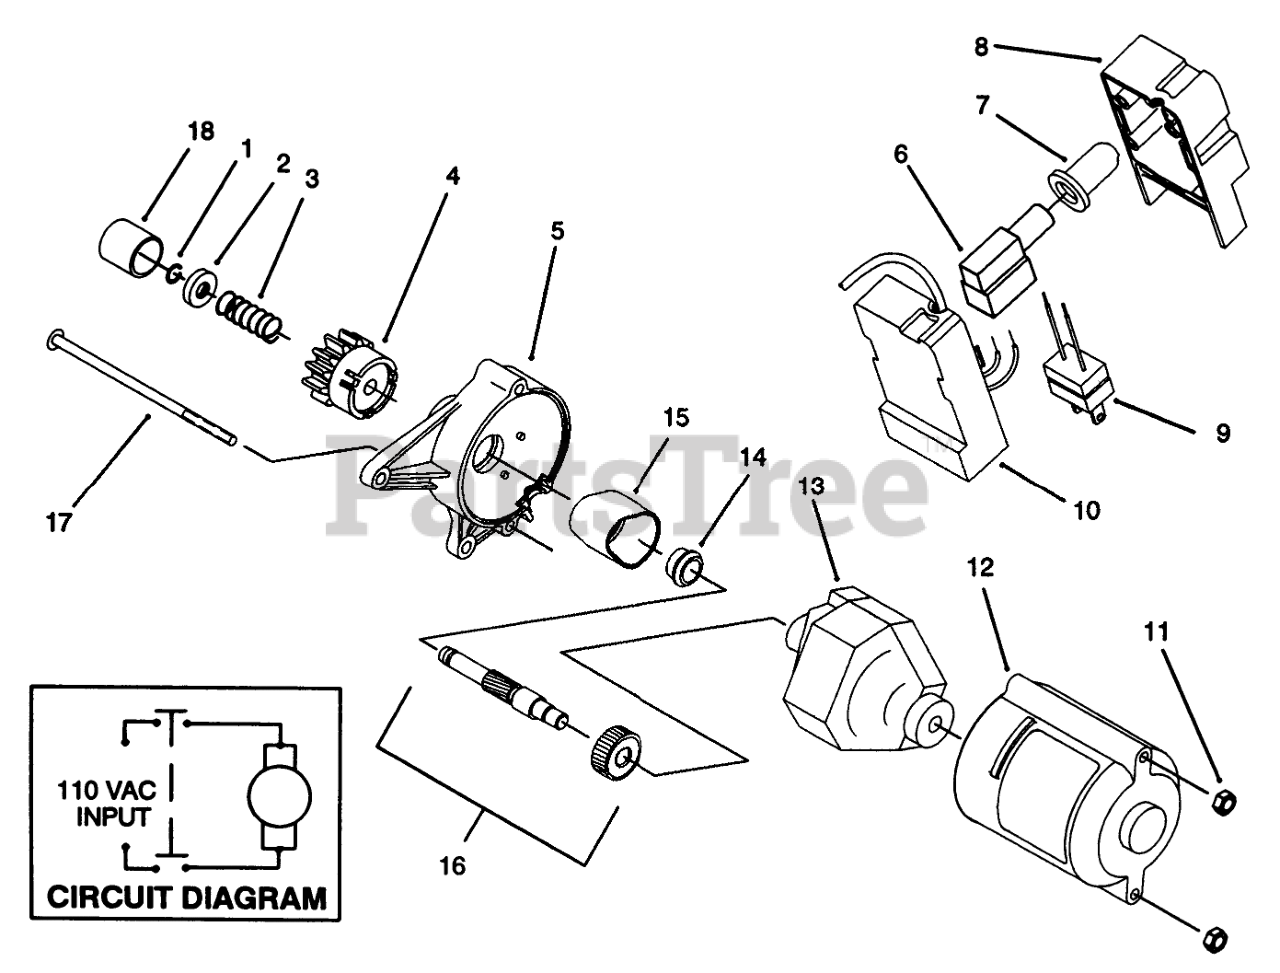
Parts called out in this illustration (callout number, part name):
1	RING-LOCK
2	PINION STOP
3	SPRING
4	PINION ASM
5	Housing-Starter
6	SWITCH-STARTER
7	BOOT-SWITCH
8	Cap-Switch Housing
9	Plug
10	OBS BASE X
11	NUT-LOCK, NI
12	HOUSING COVER
13	STARTER MOTOR ASM
14	BUSHING
15	COVER-GEAR
16	Asm-shaft & Gear
18	CAP-PINION
